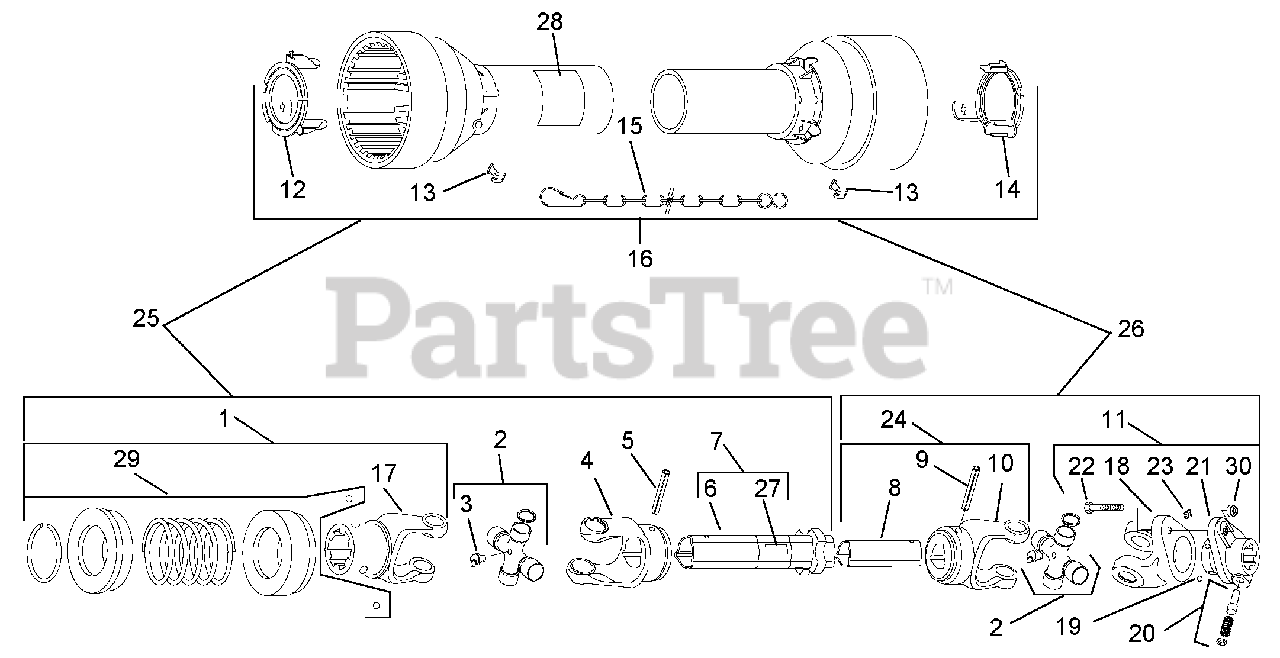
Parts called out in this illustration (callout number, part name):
1	Yoke, Outer Tube (Includes Items 17 and 29)
2	Kit, Cross and Bearing (Includes Item 3)
3	Fitting, Grease 45-Degree 8 mm x 1 mm x .88-In.
4	Yoke, Outer Tube
5	Rollpin, Inner Tube
6	Bushing With Grease Fitting
7	Tube, Complete Outer (Includes Items 6 and 27)
8	Tube, Inner
9	Roll Pin, Inner Tube
10	Yoke, Inner Tube
11	Bolt, Complete Shear (Includes Items 18 – 23 and 30)
12	Bearing, Outer Shield
13	Fastener, Shield
14	Bearing, Outer Shield
15	Chain, Safety
16	Guard, Complete With Instructions (Includes Items 12 – 15 and 28)
17	Yoke (Comer # 76282)
20	Push Pin, Set 1-3/8
22	Cap Screw, Hex Head M10 x 1.5 x 55
23	Zerk, Grease
24	Yoke, Male Tube With Roll Pin (Includes Items 8 – 10)
25	Shaft, Half Female With Guard (Includes Items 1, 2, 4, 5, 7, and 16)
26	Shaft, Male Half With Guard (Includes Items 2, 11, 16 and 24)
27	Decal, Driveline Danger
28	Decal, Danger
29	Kit, Ball Collar 1.38
30	Nut, Hex M10 x 1.5
